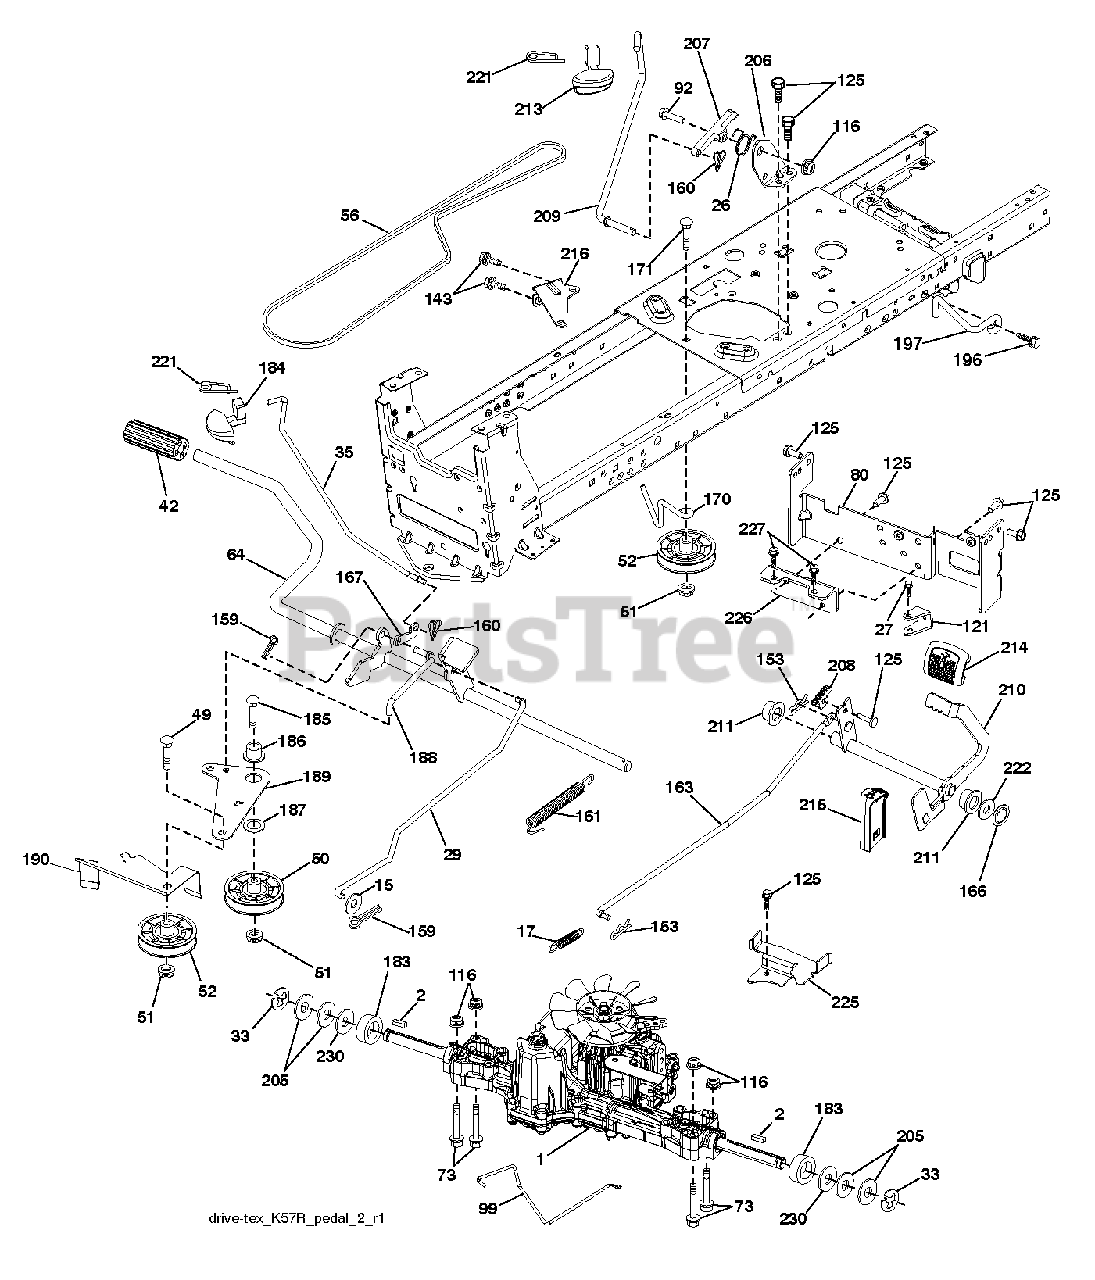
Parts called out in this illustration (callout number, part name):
2	SQUARE KEY
15	WASHER
17	SPRING.BRAKE.K46.GREEN
26	SPRING.RETURN.CRUISE
29	ROD.BRAKE.K46
35	ROD.BRAKE.PARTK.HUSQ.TEX
42	PEDAL COVER T
50	IDLER.FLAT.910.OFFSET
51	NUT LOCK FLG 3/8-16 UNC
52	IDLER.V-GROOVE.910.OFFSET
56	V-BELT.MOWER.92.40.42/K46
64	SHAFT.ASM.PEDAL.BRK.CNTR
80	STRAP.TORQUE.K46.K57R.TT
92	BOLT
99	ROD.SPRING.BYPASS.K46.LT.Z
116	NUT LOCK HEX FLANGE 5/16-18
121	BRACKET.TORQUE.K57R.3POINT
125	SCREW
143	SCREW LT
153	RETAINER M
159	COTTER PIN
160	RETAINER CLIP
161	SPRING, RETURN LT
163	ROD.CONTROL.K57R.K46
166	NUT.PUSH.625
167	LATCH.BRAKE.SPRING
170	KEEPER.V-IDLER.CENTER.
183	SPACER AXLE
184	RB HANDLE.PARKG.BRK.HUS/PRED
186	SPACER.RETAINER
187	WASHER 12/32X2X10GA
188	RP LINK.CLUTCH.GROUND.DRIVE
189	BELLCRANK.GROUND.DRIVE.TEX.
190	KEEPER.BELLCRANK.DRIVE
196	SCREW 3/8-16X1
197	LINK.CLUTCH.ANIT-ROTAT
206	BRACKET.MOUNT.CRUISE.LATCH
207	LATCH.CONTROL.CRUISE
208	GEAR.SECTOR.CONTROL.CR
209	ROD.CONTROL.CRUISE.GT.
210	ROCKER.ASM.PEDAL.CONTR
211	BEARING.NYLON
213	KNOB.CONTROL.CRUSIE.HU
214	PEDAL.FORWARD.PAD.TEX
215	PEDAL.REVERSE.TEX.GT.4
216	BRACKET.PULLEY.IDLER.W/TEX
221	RETAINER.SPRING.CLIP.H
222	WASHER 21/32 X 1-1/4 X 10 GA.
225	KEEPER.BELT.TRANSAXLE.K46
226	BRACKET.MOUNT.TORQUE.K46.TLT
227	SCREW
230	WASHER.HARDENED
